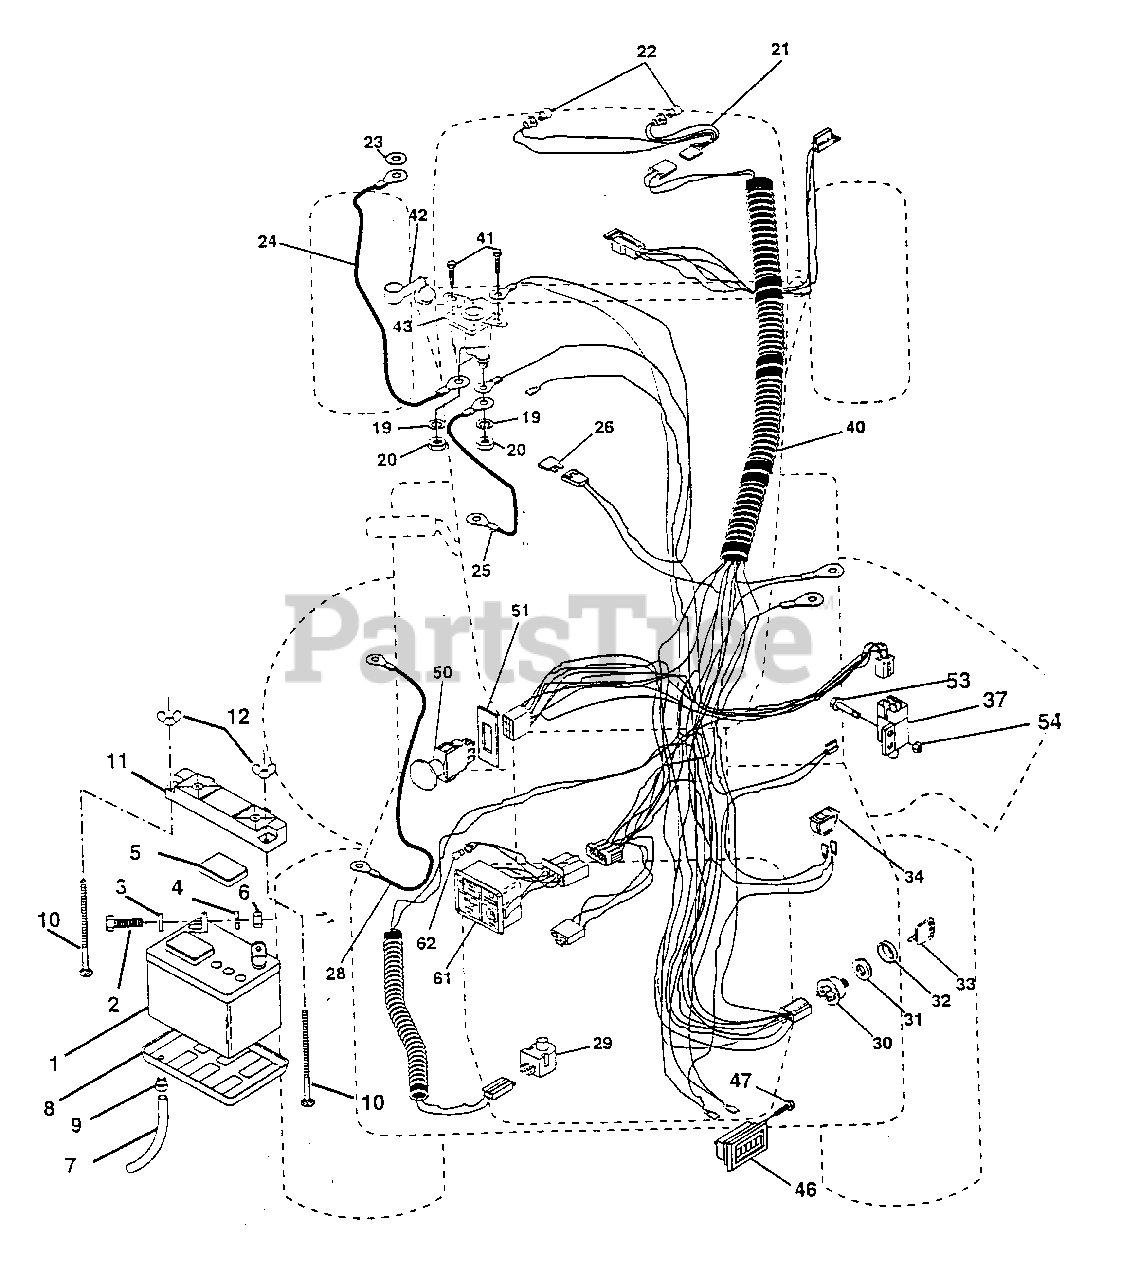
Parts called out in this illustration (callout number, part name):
1	Battery (AYP part number)
2	Bolt Hex Head 1/4-20 x 3/4 (AYP part number)
3	Washer, Lock 1/4 (AYP part number)
4	Washer 9/32 x 5/8 x 16 Ga (AYP part number)
5	Caps, Battery (AYP part number)
6	Nut Fin Hex 1/4-20 (AYP part number)
7	Tube Plastic (AYP part number)
8	Tray, Battery (AYP part number)
9	Clamp, Hose (AYP part number)
10	Bolt, Carriage 1/4-20 x 7-1/2 (AYP part number)
11	Guard Terminal (AYP part number)
12	Nut, Wing 1/4-20 (AYP part number)
19	Washer, Lock 1/4 (AYP part number)
20	Nut, Jam Hex 1/4-20 (AYP part number)
21	Harness Socket Light (AYP part number)
22	Bulb Light (AYP part number)
23	Washer, Lock Int. Tooth 1/4 (AYP part number)
24	Cable, Starter (AYP part number)
25	Cable, Battery (AYP part number)
26	Fuse (AYP part number)
28	Cable, Ground (AYP part number)
29	Switch, Plunger (AYP part number)
30	Switch, Ign (AYP part number)
31	Nut, Ignition Switch (AYP part number)
32	Cover Switch Key (AYP part number)
33	Key (AYP part number)
34	Switch, Light (AYP part number)
37	Intlk Switch (AYP part number)
40	Harness Ign. (AYP part number)
41	Screw 1/4-20 x 1/2 (AYP part number)
42	Cover, Terminal Red (AYP part number)
43	Solenoid (AYP part number)
46	Meter Hour (AYP part number)
47	Screw #10-24 x 1/2 (AYP part number)
50	Switch, PTO (AYP part number)
51	Ring Retainer PTO (AYP part number)
53	Screw Hex Washer Hd #10-32 x 1 (AYP part number)
54	Nut Keps #10-32 (AYP part number)
61	Light Pkg Asm (AYP part number)
62	Bulb, Light Pkg. (AYP part number)
